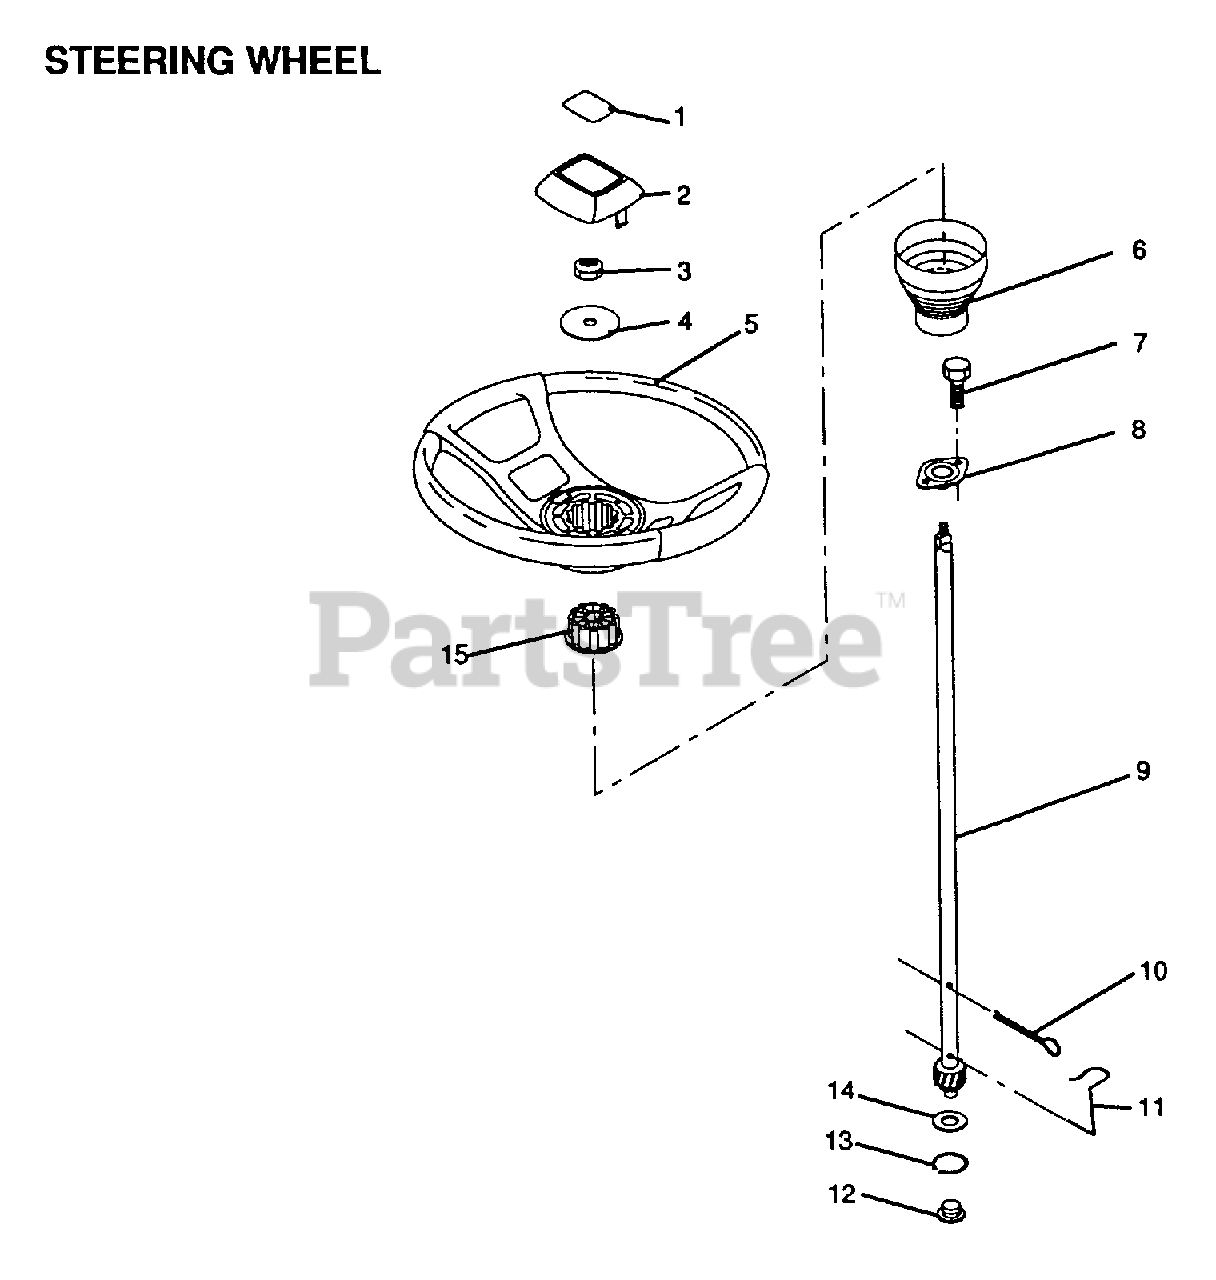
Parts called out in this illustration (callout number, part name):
2	INSERT-WHEEL LT
3	GRIPCO NUT
4	WASHER T
6	SLEEVE STEERING
11	STEERING CLIP
12	BUSHING STEER LWR
13	RING
14	WASHER LT
15	ADAPTER-WHEEL LT
